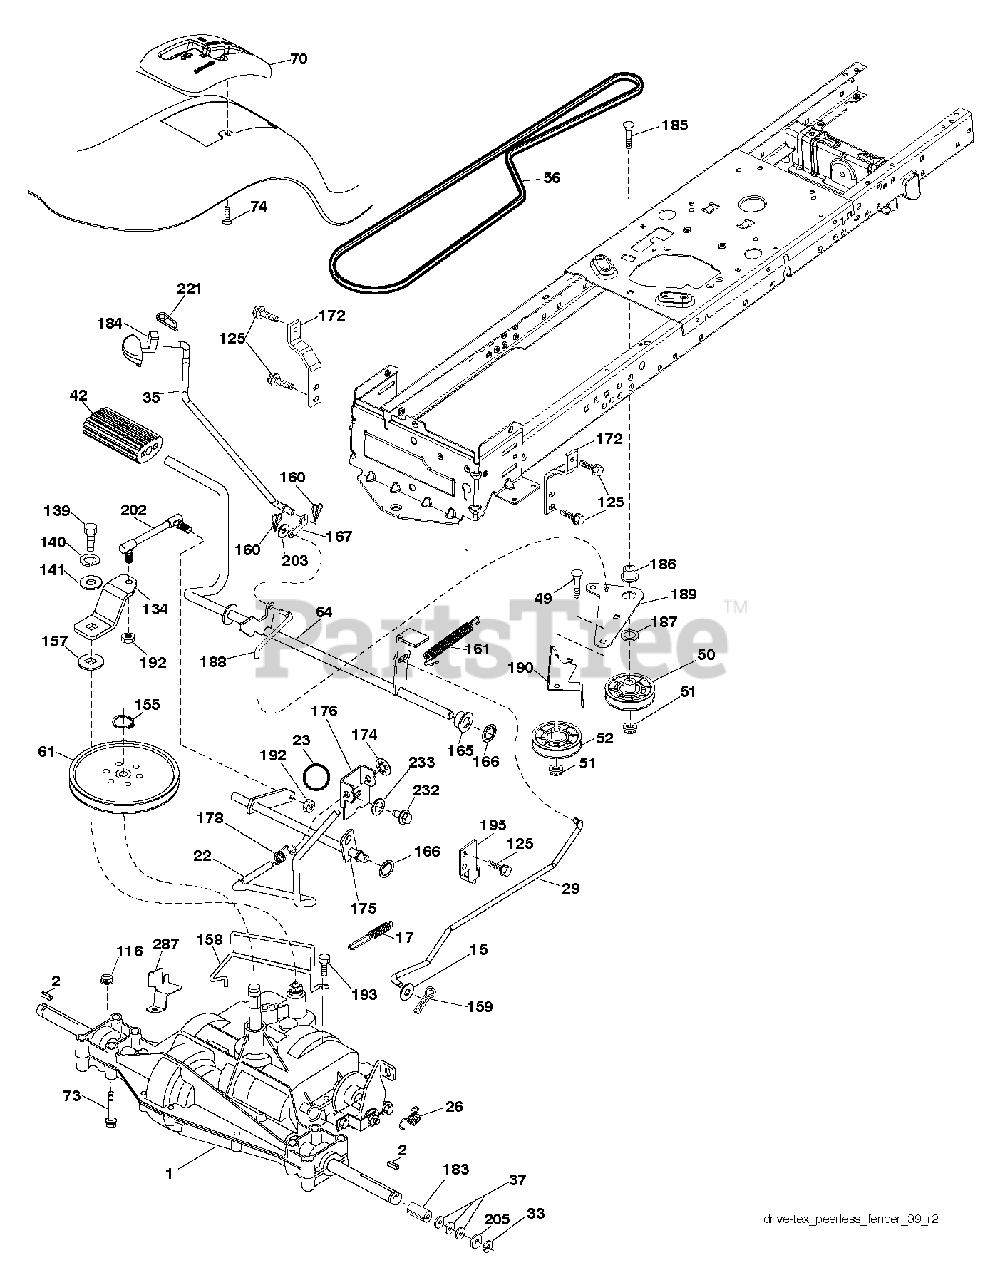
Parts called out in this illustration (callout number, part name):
2	SQUARE KEY
17	SPRING.BRAKE.PEERLESS.TEX
22	ROD.SHIFT.FENDER.TLT.2006
23	KNOB T (1/2-HOLE)
26	SPRING.BRAKE.RTN.GR.DR
29	ROD.BRAKE.PEERLESS
33	E-RING LT
35	ROD.BRAKE.PARKING.LT.T
49	BOLT
50	IDLER.FLAT.910.OFFSET
51	NUT LOCK FLG 3/8-16 UNC
52	IDLER.V-GROOVE.910.OFFSET
56	BELT, V GROUND DRIVE 95 25
64	SHAFT.ASM.PEDAL.BRAKE.
70	CONSOLE.SHIFT.STL.6SP.BLACK.T
74	SCREW.HI-LO.CONSOLE
116	NUT LOCK HEX FLANGE 5/16-18
125	SCREW
134	ARM SHIFT
139	Bolt, 1/4-20 unf Grade 8 w/Patch
140	LOCKWASHER
141	WASHER LT
155	RETAINING RING LT
157	WASH-SHFT PLT LT
158	KEEPER.PMS.18/20.D4365
159	COTTER PIN
160	RETAINER CLIP
161	SPRING, RETURN LT
165	BUSHING.SHAFT.BRAKE.HAND
166	NUT.PUSH.625
167	LATCH.BRAKE.SPRING
172	STRAP.TRQ.LH.GEAR.DRIV
174	NUT.PUSH.500.2006
175	SHAFT ASM SHIFT
176	ARM.CLEVIS.ROD.SHIFT
178	SPRING.SHIFT.GT2006
183	SPACER AXLE
184	HANDLE.PARKING.BRAKE.LTTEX.667
186	SPACER.RETAINER
187	WASHER 12/32X2X10GA
188	LINK.CLUTCH.GROUND.DRIVE
189	BELLCRANK.GROUND.DRIVE.TEX.
190	KEEPER.BELLCRANK.DRIVE
192	NUT LOCK CENTER 1/4 -28 FNTHD
193	SCREW 5/16"
195	BRKT.ROD.BRAKE.PEERLES
202	LINK.SHIFT.PMST.18" (SPG1286)
203	WASHER
221	RETAINER.SPRING.CLIP.H
232	BOLT FIN HEX 7/16-14 X 1
233	WASHER SERRATED
287	KEEPER.PULLEY.T/A.7.04
